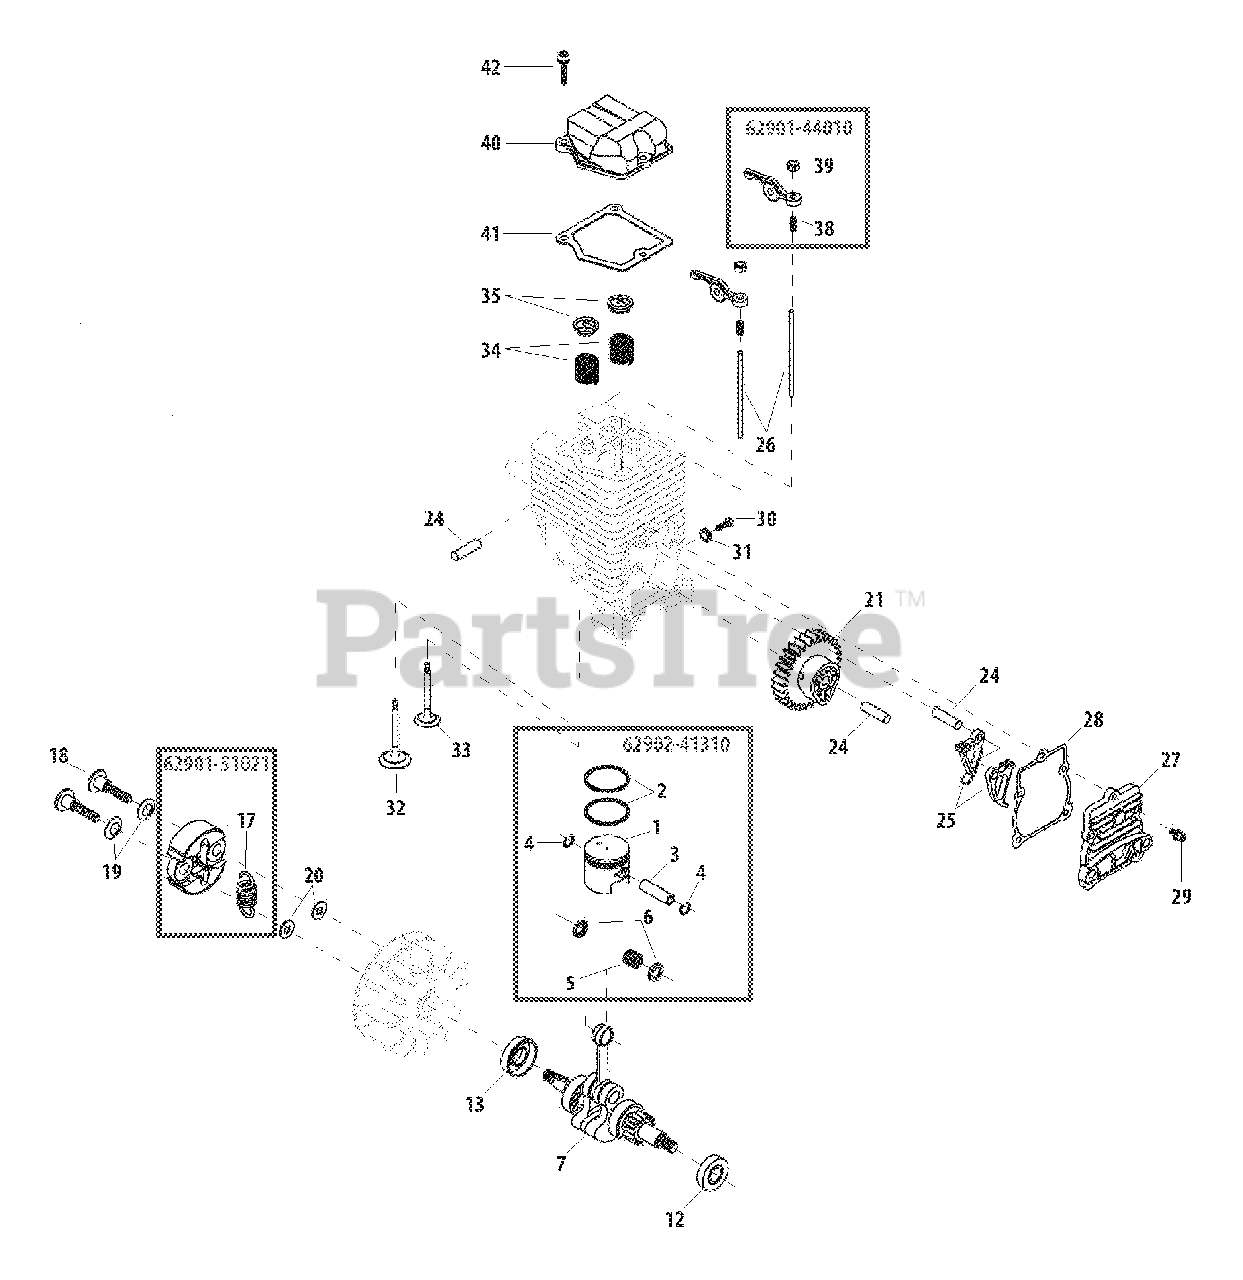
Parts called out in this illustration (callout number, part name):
1	PISTON
2	RING, PISTON
3	PIN, PISTON
4	RING, RETAINING
5	BEARING, NEEDLE
6	SPACER - 9
7	CRANKSHAFT ASSY
12	SEAL, OIL - 12
13	SEAL, OIL - 12
17	SPRING, CLUTCH
18	BOLT, CLUTCH
19	WASHER - SPRING
20	WASHER - 6
21	GEAR, CAM
24	PIN - LOCATING
25	FOLLOWER, CAM
26	PUSHROD
27	COVER, CAM GEAR
28	GASKET
29	SCREW - 4X14
30	SCREW - 5
31	WASHER
32	VALVE, INTAKE
33	VALVE, EXHAUST
34	SPRING, VALVE
35	VALVE RETAINER ASSY
38	SCREW, ADJUST
39	LOCKNUT, ADJUSTER
40	COVER, ROCKER ARM
41	GASKET
42	SCREW - 4X12
62901-44010	ROCKER ARM ASSY
62901-51021	CLUTCH ASSY
62902-41310	PISTON KIT
